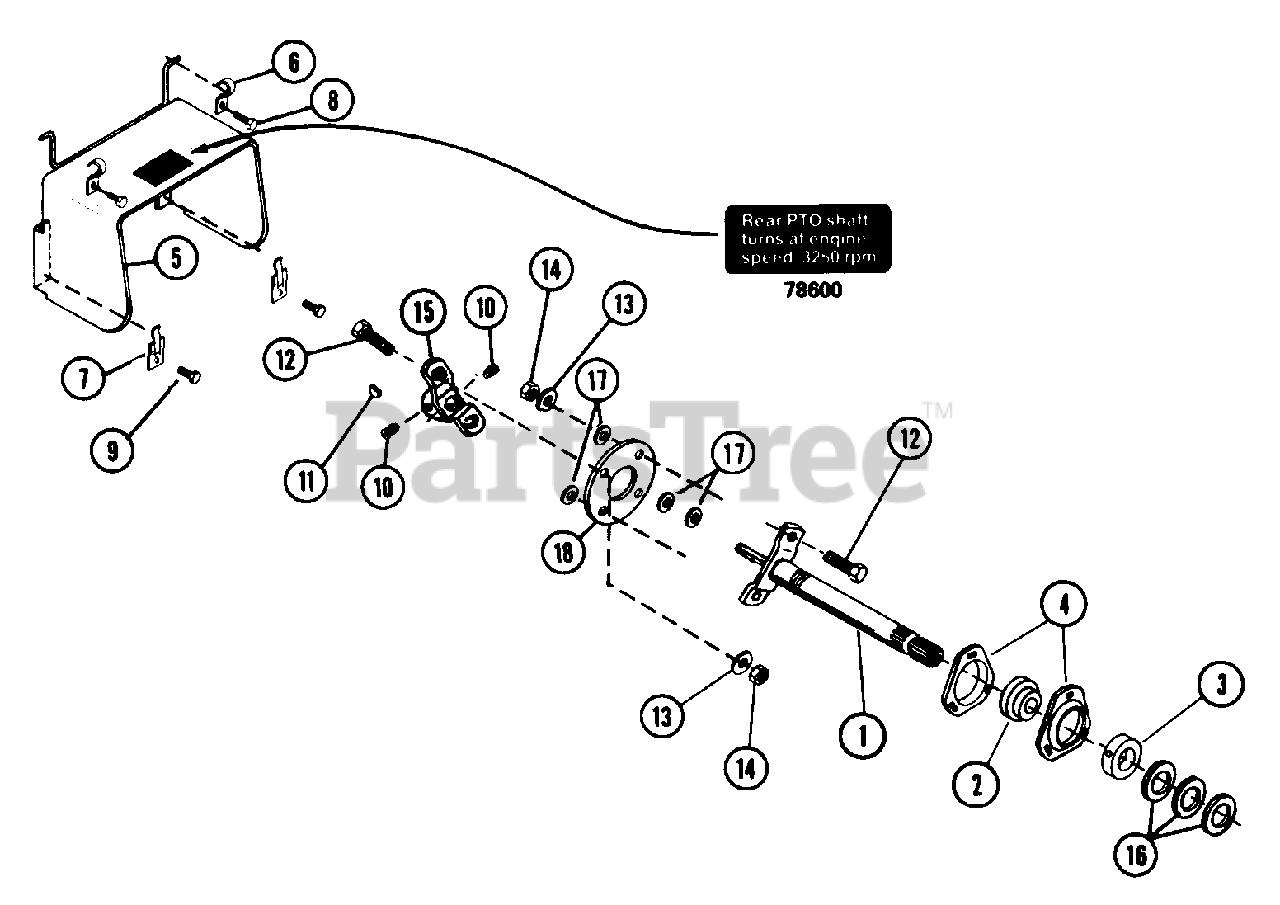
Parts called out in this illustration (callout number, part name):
1	REAR PTO SHAFT ASSEMBLY
2	BRG/W COLLAR 1.0 X 2.047 X.844
3	BEARING COLLAR
4	BEARING FLANGE
5	PTO SHIELD
7	SNAP FASTENER
8	SCR-TAP .250-20X.50 HXSLHDPL
9	SCR-TAP 10-24X.375 HWH PL TR
10	SCR-SET .32-18X.38 SKHCUPNL OH
11	KEY-WDRF .188X.75X.313 SAE 9
12	BLT-HEX .31-18X1.00 PL GR 2
13	WSHR-FL-STL.344X.688X.065PL
14	NUT-LK .312-18 GR A PL
15	COUPLING
16	SPACER-SPECIAL CONICAL
17	SPACER .380X.750X.236
18	SPACER COUPLING
